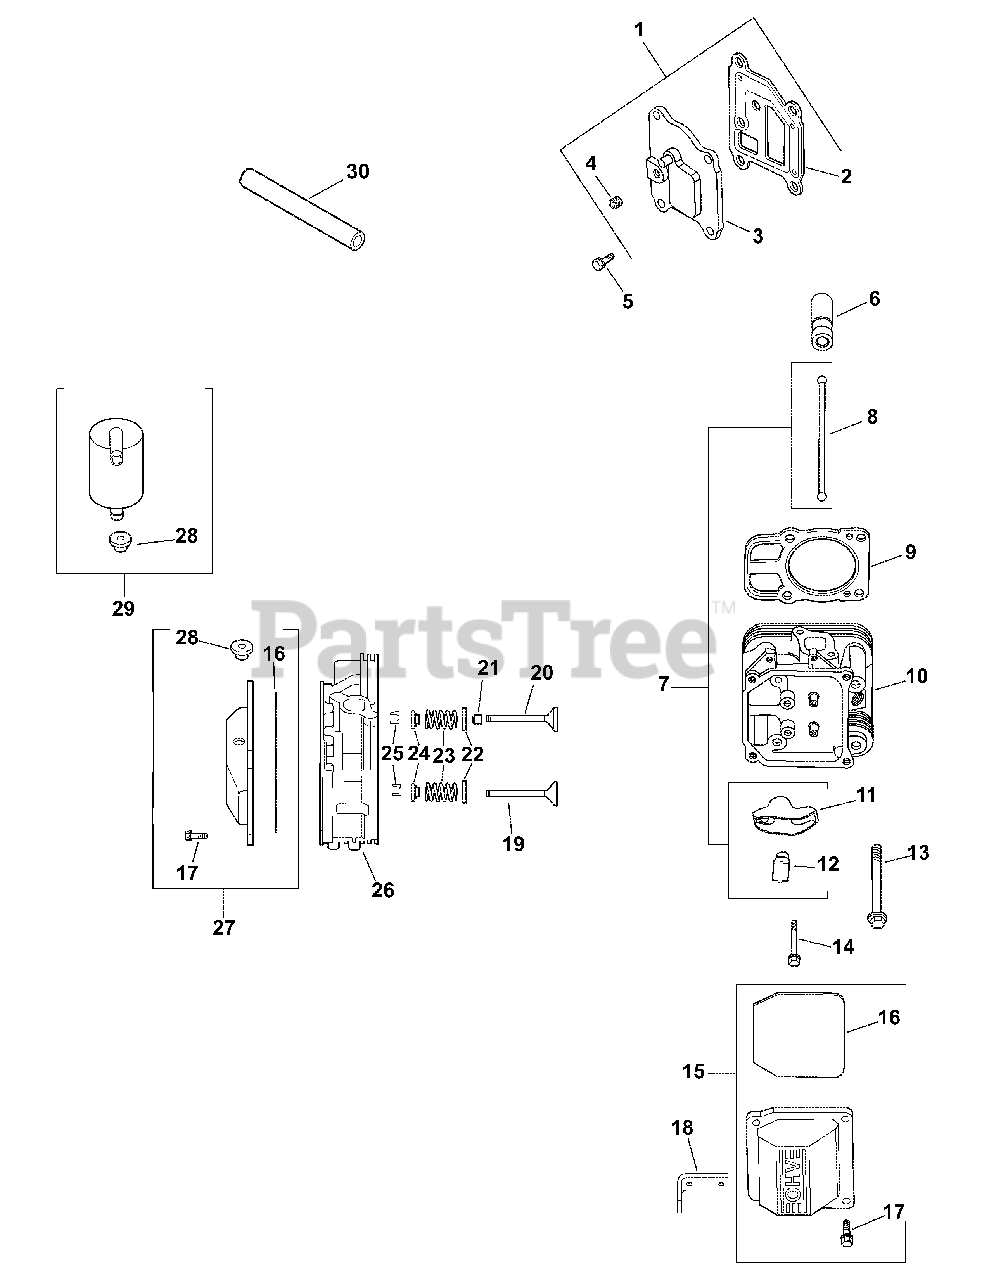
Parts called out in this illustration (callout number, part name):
1	KIT, BREATHER COVER W/GASKET
2	GASKET, BREATHER
3	COVER, BREATHER
4	PLUG, CTSK PIPE 1/8"
5	SCREW, FLG THD FRM M6X1.0X20
6	KIT, HYDRAULIC VAVLE LIFTER
7	KIT, VALVE TRAIN
9	KIT, GASKET CYLINDER HEAD
10	KIT, HEAD #2
12	PIVOT, ROCKER ARM
13	SCREW, FLG M10X1.5X90
14	SCREW, FLG M6X1.0X34
15	KIT, VALVE COVER-PLAIN
16	O-RING, VALVE COVER
17	SCREW, FLG M6X1.0X30
18	STRAP, LIFTING
19	VALVE, EXHAUST (STD)
19	VALVE, EXHAUST (.25)
20	VALVE, INTAKE (STD)
20	VALVE, INTAKE (.25)
21	SEAL, VALVE STEM
22	RETAINER, SPRING
23	SPRING, VALVE
24	CAP, VALVE SPRING
25	KIT, RETAINER
26	KIT, HEAD #1
27	KIT, VALVE COVER BREATHER
28	GROMMET, RUBBER
29	KIT, BREATHER SEPERATOR
30	HOSE, BREATHER
